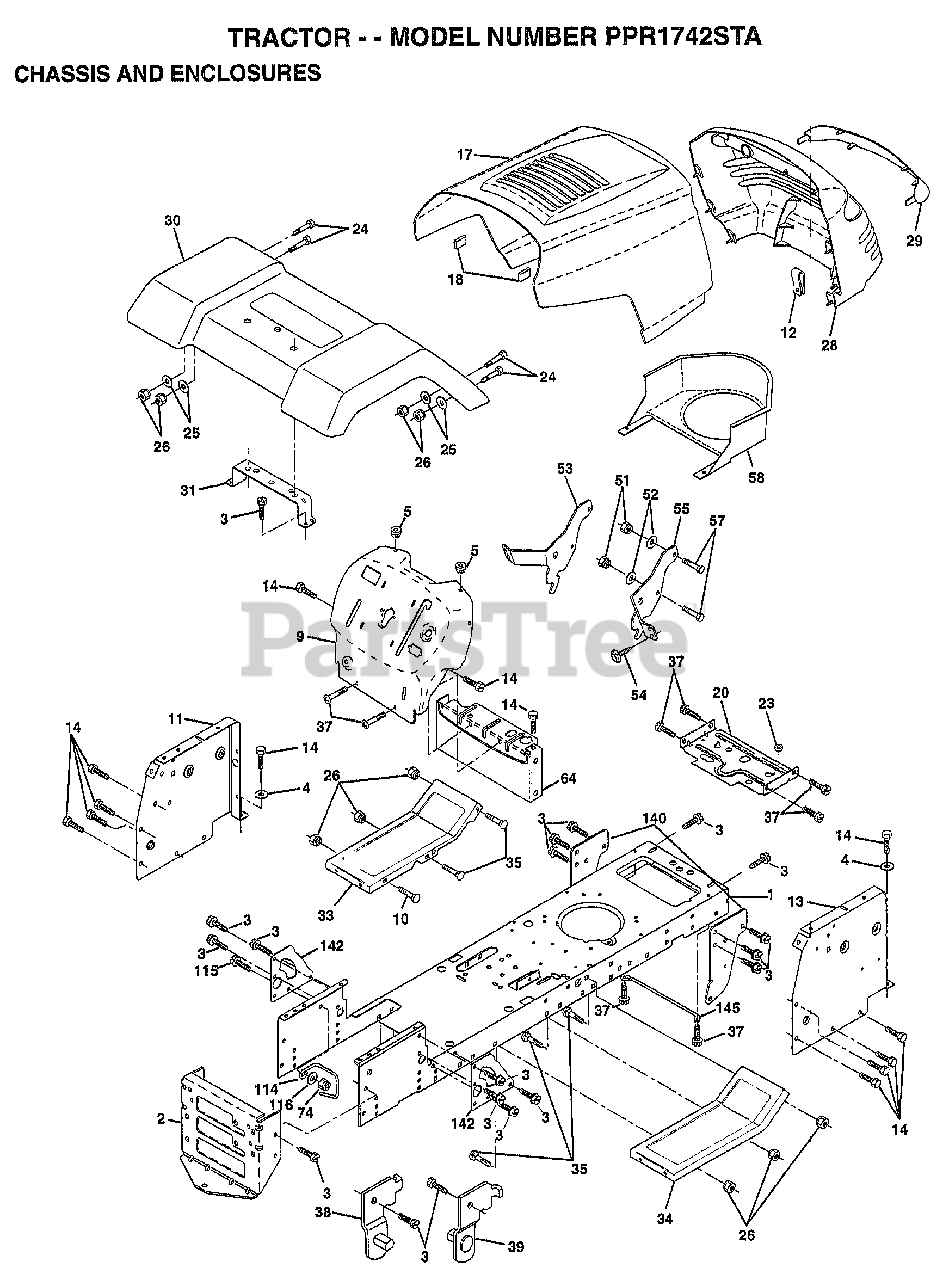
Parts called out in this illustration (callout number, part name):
1	CHASSIS.STLT.STAMPING
3	SCREW
4	WASHER
5	BUMPER-HOOD/DASH
11	"PANEL-DASH,LH"
12	CLIP.TINNERMAN
13	PANEL.ASM.DASH.RH
14	SCREW LT
17	"HOOD W/TRIM,MS428"
20	"PLATE-MTG,BATT/FU"
24	BOLT
25	WASHER
26	NUT
28	GRILL
29	GRILLE.LENS
30	FENDER.FOOTREST.SPLT.PNT
31	BRACKET SUPT FEND
33	FOOTREST PNT LH
34	FOOTREST.RH.LT/GT
35	BOLT
37	SCREW LT
38	BRACKET ASM LH
39	BRACKET ASM RH
51	NUT
52	WASHER
53	BRACKET.GRILLE.LH
54	SCREW.HEX.WS.HD
55	BRACKET.GRILLE.RH
58	AIR DUCT
64	DASH-LOWER
114	"KEEPER-BELT,RR.LH"
115	SCREW
116	WASHER
140	BRKT SUSPENSION
142	PLATE.REINFORCEMENT
145	"ROD POVOT,CHASSIS"
